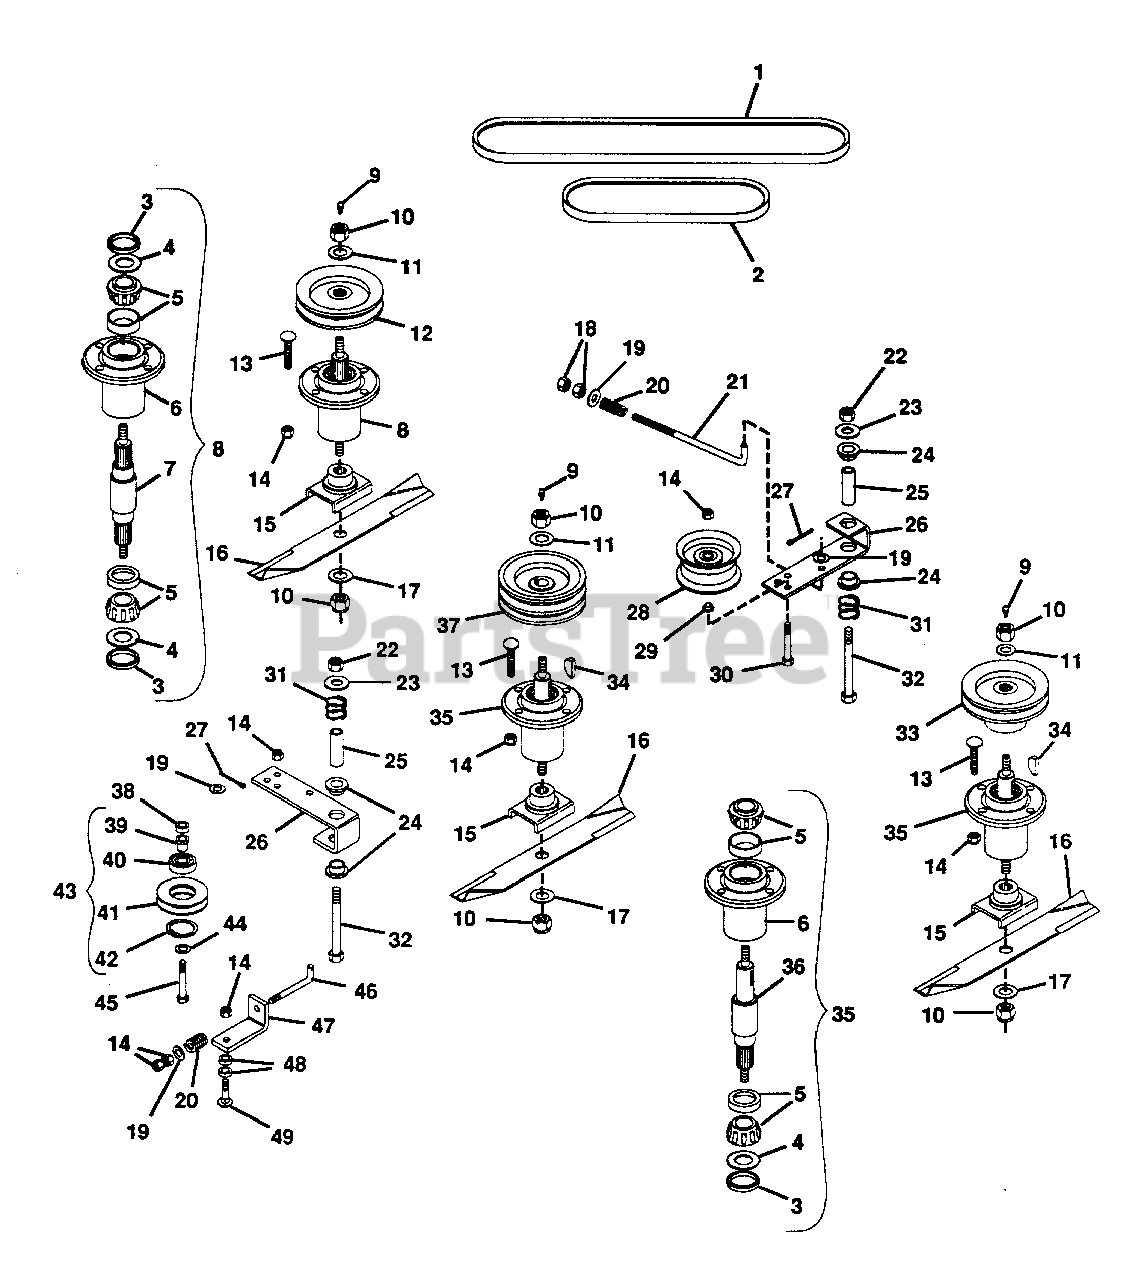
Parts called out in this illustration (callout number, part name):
1	BELT, V
2	BELT, V
3	SEAL, STEEL(IN 34605)
3	SEAL, STEEL(IN 21306)
4	WASHER, FLAT .975X1.970X.030(IN 34605)
4	WASHER, FLAT .975X1.970X.030
5	ASSEMBLY, BEARING
6	HOUSING, BEARING
7	SHAFT, SPINDLE
8	ASSEMBLY, SPINDLE
9	FITTING, LUBE 1/8
10	NUT, LOCK 5/8-11
11	WASHER, FLAT .687X1.312X.122
12	PULLEY
13	BOLT, 3/8-16X1.375 RD HD SQ NK
14	NUT, LOCK 3/8-16
15	WELDMENT, BLADE CRADLE
16	BLADE
17	WASHER, FLAT .656X1.312X.095
18	NUT, HEX 3/8-24
19	WASHER, FLAT .406X.812X.065
20	SPRING, COMP. 1X.78
21	ROD, IDLER
22	NUT, LOCK 1/2-13
23	WASHER, FLAT .531X1.250X.100
24	BUSHING, NYLON .76X1X.6 FLG.
25	SPACER
26	ARM, IDLER PIVOT
27	PIN, COTTER .09X.75
28	PULLEY, IDLER
29	BUSHING
30	BOLT, HEX 3/8-16X2.25
31	SPRING, COMP. 1X.80X36 LB/N
32	BOLT, HEX 1/2-13X3.25
33	SHEAVE, SPINDLE
34	KEY, WOODRUFF .250X1 HARD #15
35	ASSEMBLY, SPINDLE
36	SHAFT, SPINDLE
37	SHEAVE, SPINDLE
38	SPACER, IDLER .406X.625X.48
39	BUSHING, IDLER SHEAVE
40	BEARING, BALL
41	SHEAVE, IDLER
42	RING, RETAINING
43	ASSEMBLY, IDLER SHEAVE
44	WASHER, FLAT .375X1.125X.065
45	BOLT, HEX 3/8-16X2.00
46	ROD, IDLER
47	BRACKET, BELT TENSIONER
48	SPACER
49	BOLT, 3/8-16X1.75 RD HD SQ NK
